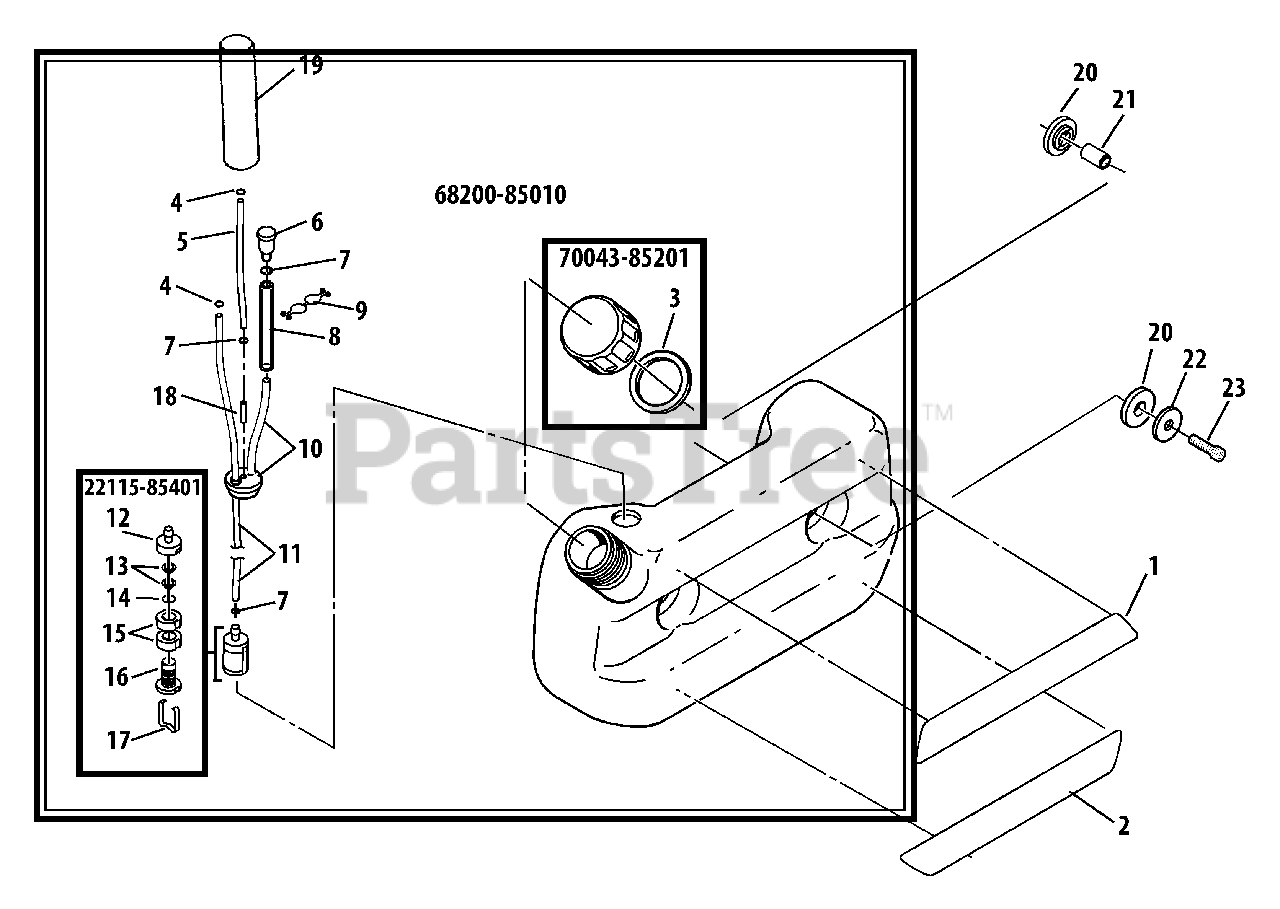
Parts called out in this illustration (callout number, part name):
1	LABEL - MODEL
2	LABEL, SHINDAIWA
3	GASKET, FUEL CAP
4	CLIP
5	PIPE, FUEL RETURN
6	VENT ASSY
7	CLIP Ø6
8	TUBE, INSULATOR
9	CLIP
10	GROMMET, FUEL W/VENT PIPE
11	TUBE
12	WEIGHT, FUEL LINE
13	SCREEN, FILTER
14	RING, RETAINING
15	FILTER, FUEL
16	BODY, FUEL FILTER
17	CLIP, FILTER
18	CONNECTOR, PIPE
19	TUBE, INSULATOR
20	CUSHION
21	BUSHING
22	COLLAR Ø23ר6.5×L3.2
23	BOLT M6×25
22115-85401	FILTER, FUEL
68200-85010	FUEL TANK ASSY
70043-85201	CAP ASSY, FUEL
